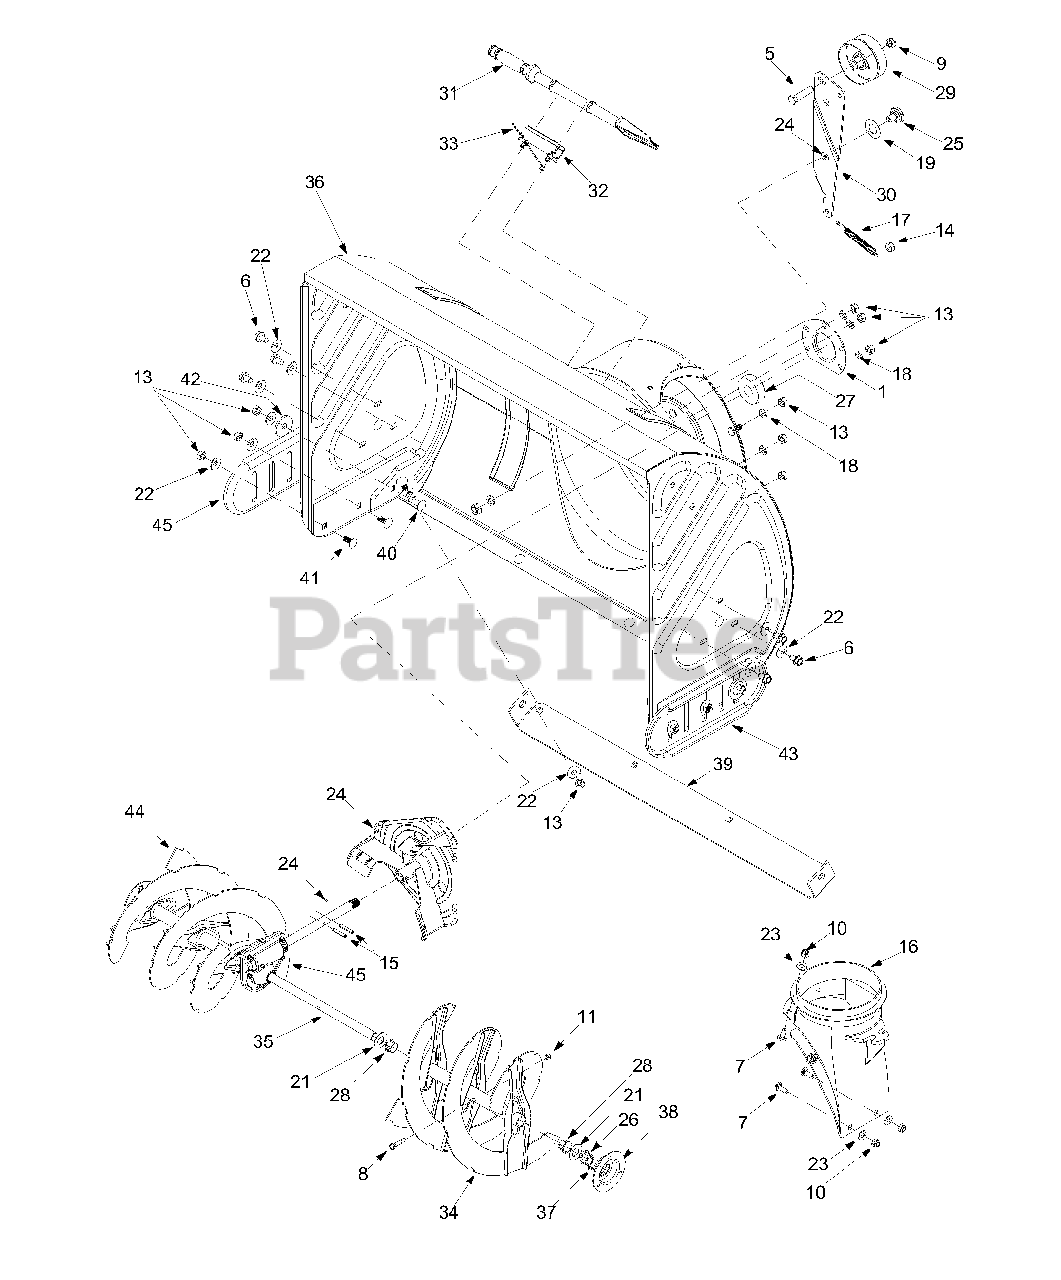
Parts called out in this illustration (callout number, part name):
1	Bearing Housing
5	Hex Bolt 3/8-24 x 1.5"
6	TT Screw 5/16-18 x 0.625"
7	Carriage Screw 1/4-20 x 0.75"
8	Shear Bolt
9	Lock Nut 3/8-24
10	Lock Nut 1/4-20
13	Hex Nut 5/16-18
14	Hex Lock Nut
15	Spring Pin
16	Chute Adapter
17	Extension Spring
18	Lock Washer
19	Flat Washer
21	Flat Washer
22	Bell Washer
23	Flat Washer
24	Grease
25	Shoulder Screw
26	Hex Flange Bearing
27	Ball Bearing
28	Flange Bearing
29	Flat Idler
31	Chute Clean-Out Tool
32	Tool Mount
33	Cable Tie
38	Bearing Housing
40	Carriage Screw 5/16-18 x 1.0"
41	Carriage Bolt 5/16-18 x 0.75"
42	Flat Washer .38 x 1.38 x .125
45	Gear Assembly: Auger
